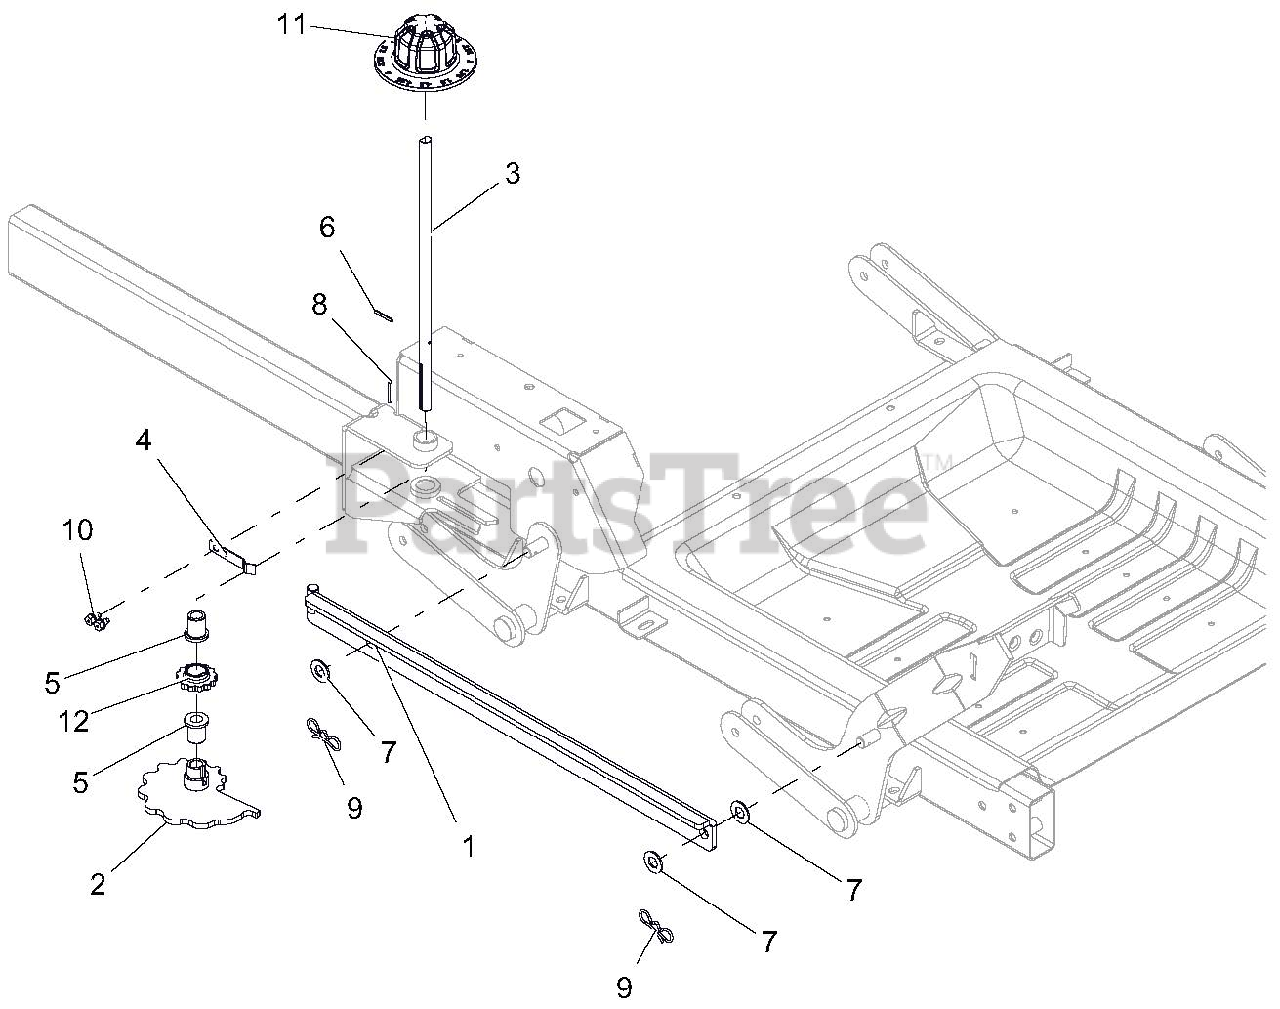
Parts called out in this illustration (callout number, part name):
1	WLDMT, HOC LINK-BLACK
2	WLDMT, HOC CAM
3	CAMSHAFT, HOC
4	ARM, HOC DETENT
5	BUSHING, FLANGE .503X.75X.875X1.0
6	PIN-ROLL .125X1.00
7	WSHR-FL-NYL .518X1.00X.08
8	KEY, 1/8 X 1/8 X 1.0 REV
9	PIN, BOWTIE LOCKING .091X1.875
10	SCR-TAP .25-20X.37 HWH YWZ TR
11	KNOB, HOC
12	CAM, HOC INDEX
